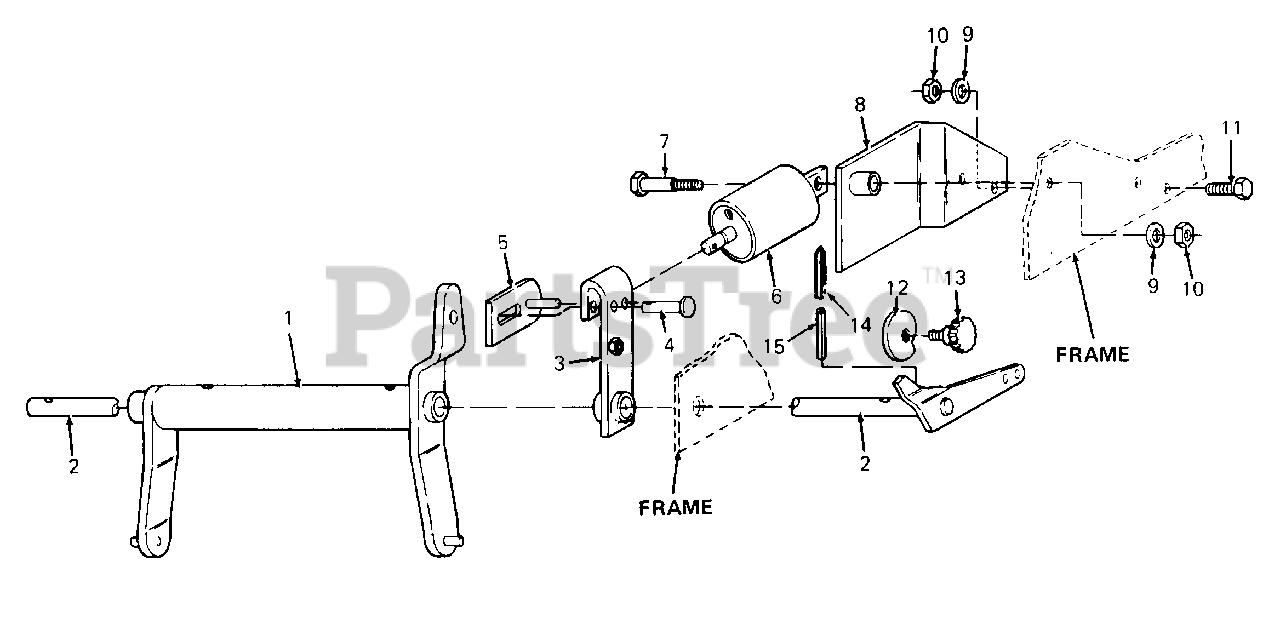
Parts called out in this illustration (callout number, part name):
1	Lift Assy, Rockshaft
2	Rockshaft Assy
3	Bracket, Lift
4	Pin, Clevis, 1/2 Dia X 2.172 Lg
5	Pin Assy, Lift
6	Cylinder, Hydraulic
7	Bolt, Shoulder
8	Bracket, Cylinder
9	Washer, Flat, .531 X 1.06 X .134 Thk
10	Nut, Hex Center Lock, 1/2-13 GR5
11	Screw, Hex Cap, 1/2-13 X 1.25 Lg GR5
14	Pointer, Lift
15	Pin, Roll, 3/16 Dia X 3.0 Lg
